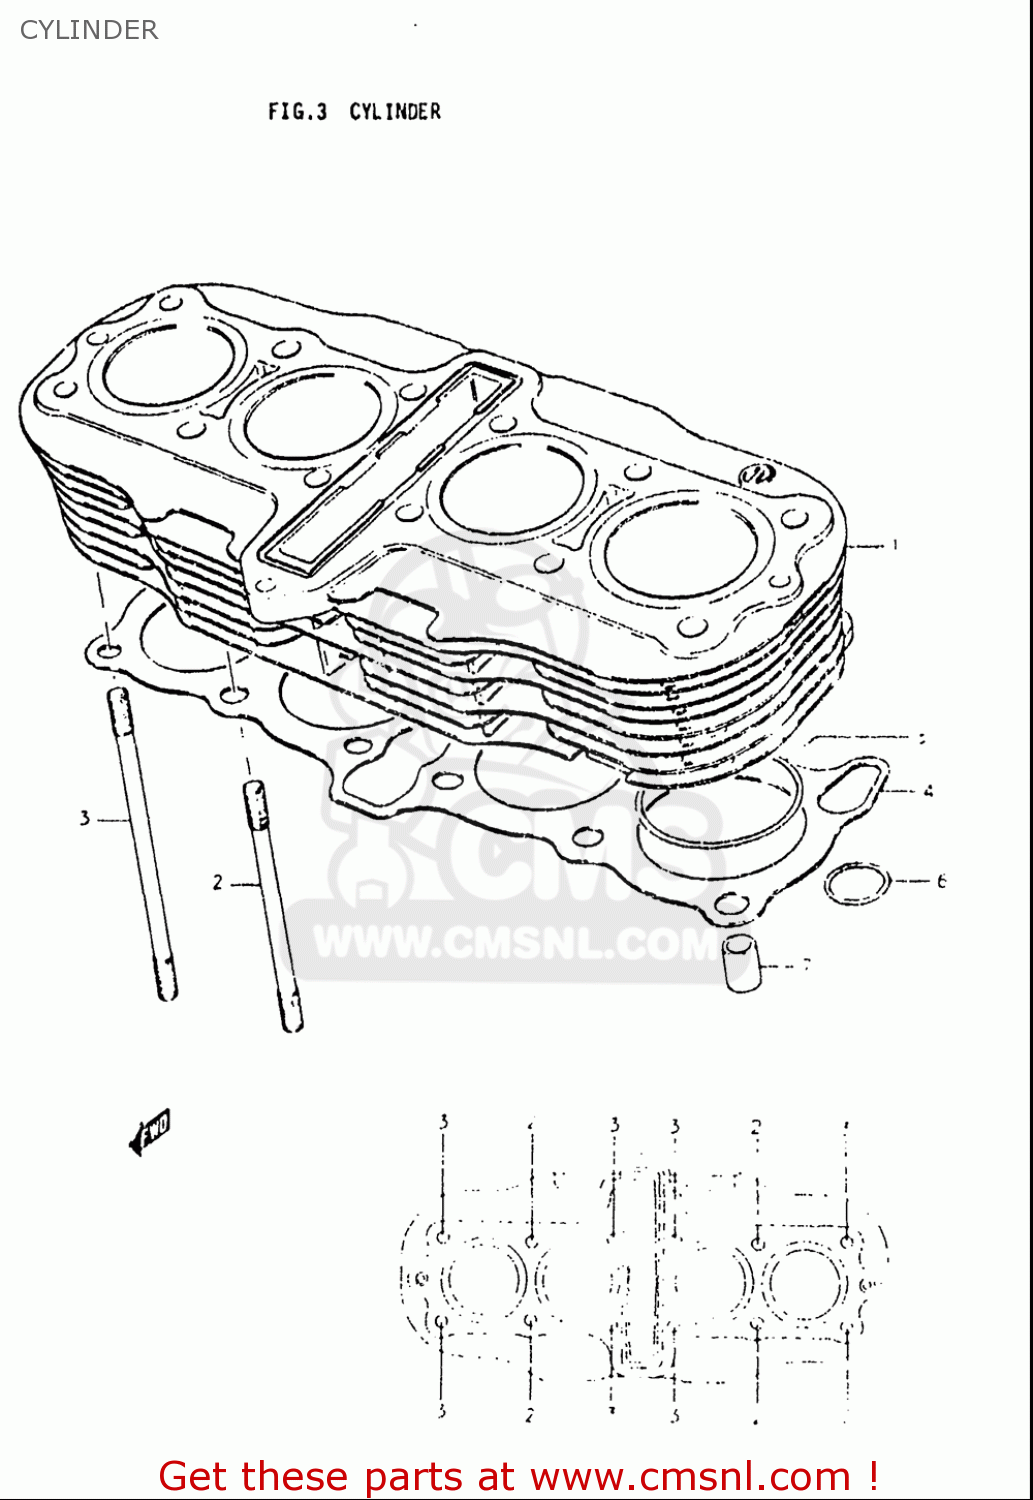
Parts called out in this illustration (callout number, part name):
2	BOLT,STUD
3	BOLT,STUD
4	GASKET,CYLINDER (NAS)
5	O RING(D:2,ID:61)
6	INVALID PARTNUMBER
7	PIN
